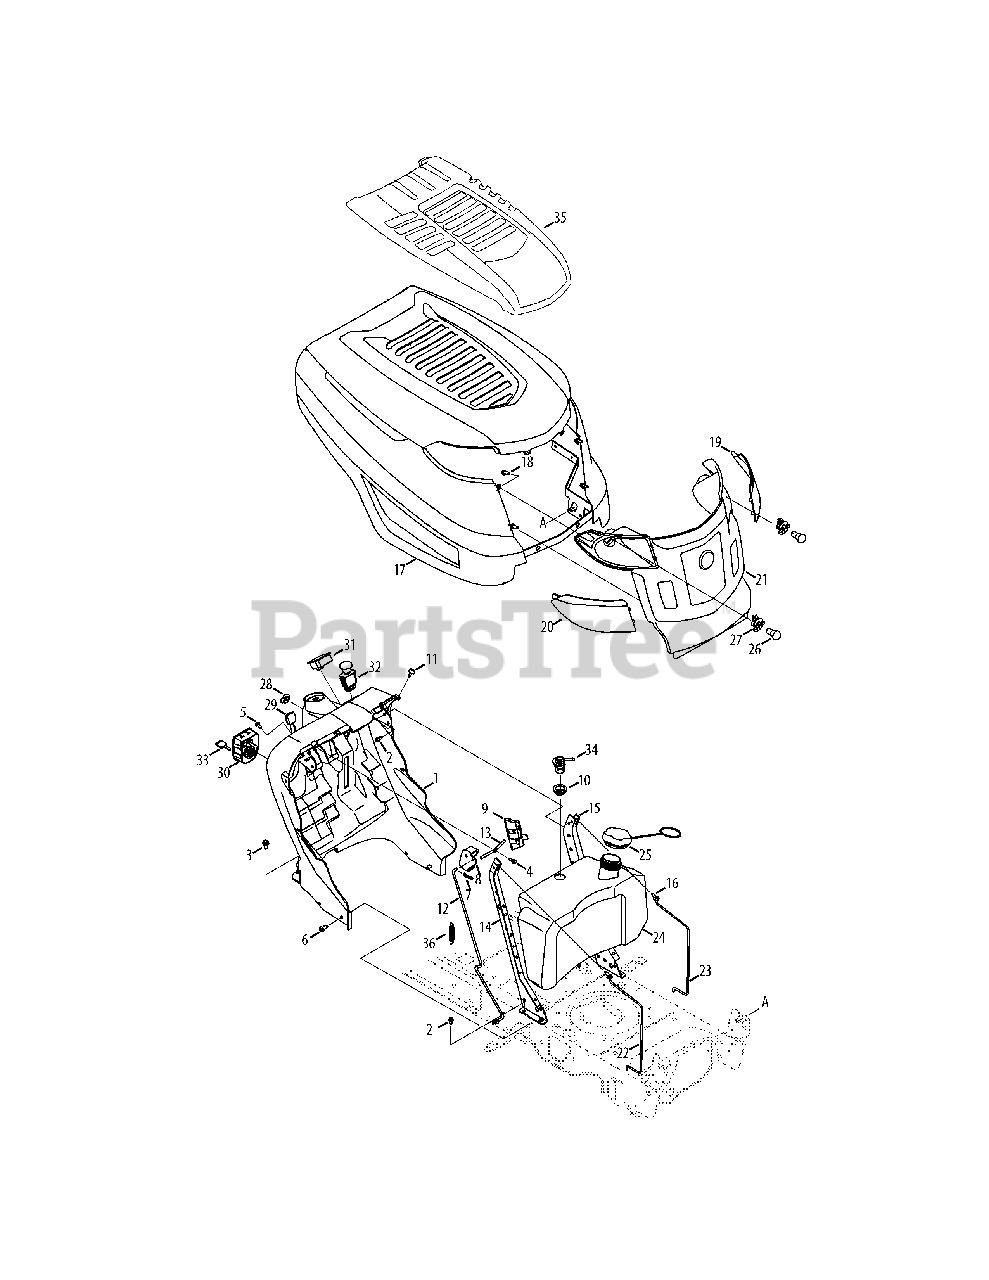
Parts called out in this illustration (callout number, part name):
1	Dash Assembly, Man. PTO
2	Taptite Screw ,1/4-20:0.500
3	Taptite Screw ,5/16-18:.750
4	Hi-Lo Screw, 1/4-15:0.750
5	Screw, 1/4-14:0.625
6	Taptite Screw ,5/16-18:0.750
7	Bow Tie Cotter Pin
8	Dash Lever
9	Cruise Cover
10	Grommet, Rubber, 23.0 ID
12	Control Rod
14	RH Support Plate
15	LH Support Plate
16	Taptite Screw, 1/4-20:0.750
17	Hood Assembly
18	Screw, 1/4 DIA:.750
22	LH Tank Support Rod
23	RH Tank Support Rod
24	Fuel Tank, w/ rollover valve
25	Fuel Cap, EPA
27	Lamp Socket
28	Choke Plug
28	Choke Cable
29	Throttle/Choke Cable
30	Key Switch Module
31	Hour Meter
32	Electric PTO Switch
34	Valve, Rollover Grommet
35	Hood Scoop
36	Extension Spring, .500 DIA x 2.733 LG
